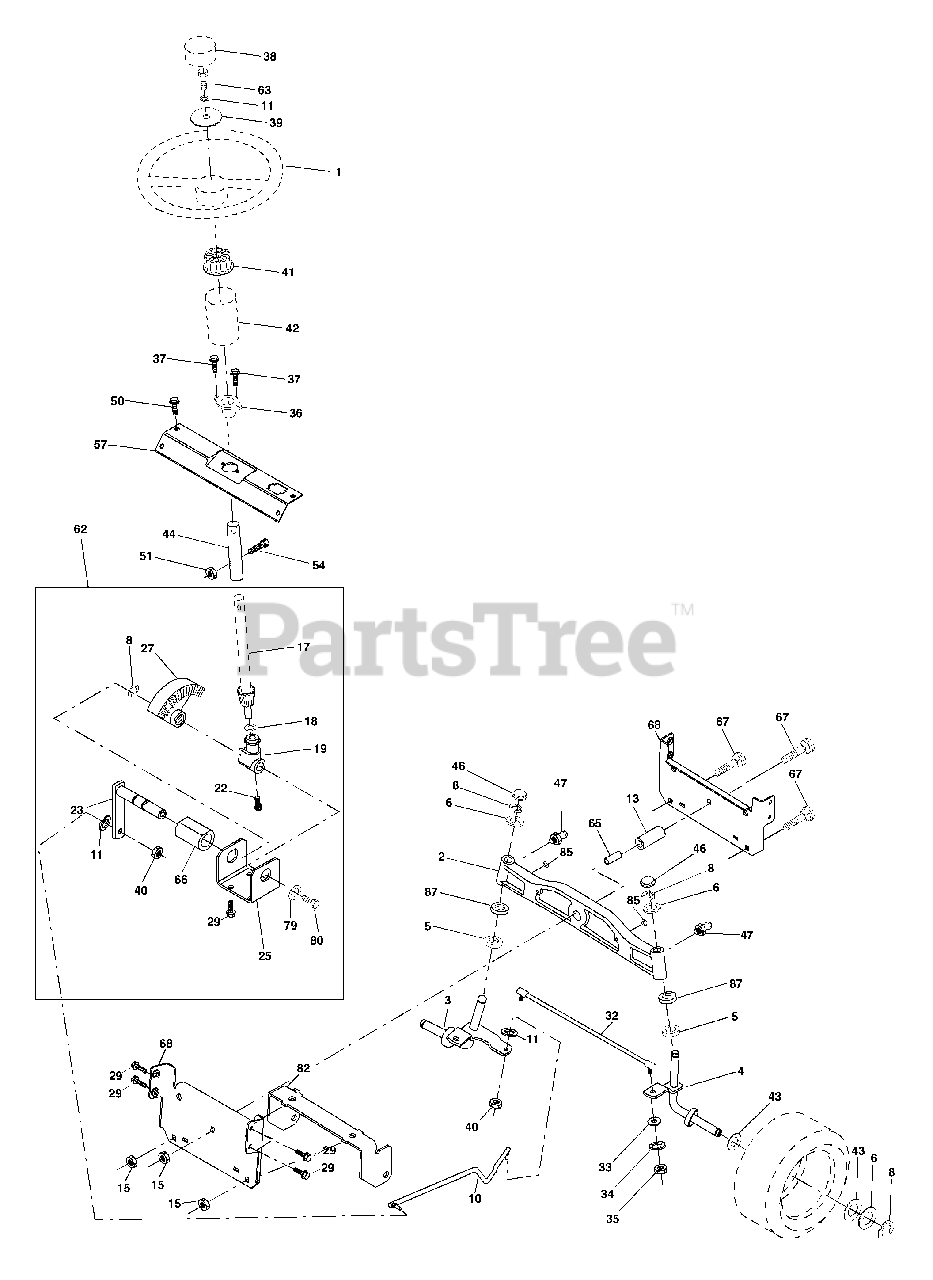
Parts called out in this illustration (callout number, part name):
1	Wheel Steering
2	Axle Cast Lt Machined
3	Spindle Asm LH
4	Spindle Asm RH
5	Bearing Race Thrust Harden
6	Washer 25/32 X 1-5/8 X 16 Ga
8	Ring Klip #t5304-75
10	Link Drag
11	Washer Lock Hvy Hlcl Spr 3/8
13	Spacer Brg Axle Front
15	Nut Hex Flange Lock
17	Shaft Asm Strg Private Label
18	Washer Thrust 515x 750x 033
19	Support Shaft
22	Screw Hex Wsh Hd Torx
23	Shaft Asm Pittman
25	Bracket Steering
27	Gear Sector 22 Teeth
29	Screw 3/8-16x3/4
32	Rod Tie
33	Washer 11/32 x 3/4 x 16 Ga.
34	Washer Lock Hry Hlcl Spr 5/16
35	Nut Crownlock 5/16 - 24 UNF
36	Bushing Strg
37	Screw TT #32.5 x 5 x 3/8 Flange
38	Cap Wheel Steer
39	Washer 13/32 x 1-1/20 x 11 Ga
40	Nut Lock Center 3/8-24 Unf
41	Adaptor Wheel Strg
43	Washer 25/32 X 1 1/4 X 16 Ga
44	Extension Steering Non-adjust
46	Cap Spindle Fr Top Blk
47	Fitting Grease
50	Screw Hexwsh Thdrol 1/4-20 x 3/4
51	Nut Lock Hex W/Ins 5/16-18 UNC
54	Bolt Fin Hex 5/16-18 UNC x 1-1/4
57	Support Shaft Steering
62	Steering Assembly
63	Bolt Fin Hex 3/8-16 UNC x 1 Gr. 5
65	Spacer Brace Axle
66	Bearing Arm Pittm-an
67	Bolt Rdhd Sqn 3/8-16 x 2-1/4
68	Brace, Axle
79	Washer 13/32 x 1-1/4 x 12 Ga.
80	Bolt Hex Nylon 3/8-16 x 3/4
82	Bracket Susp Chassis Front
85	Fastner Christmas Tree
